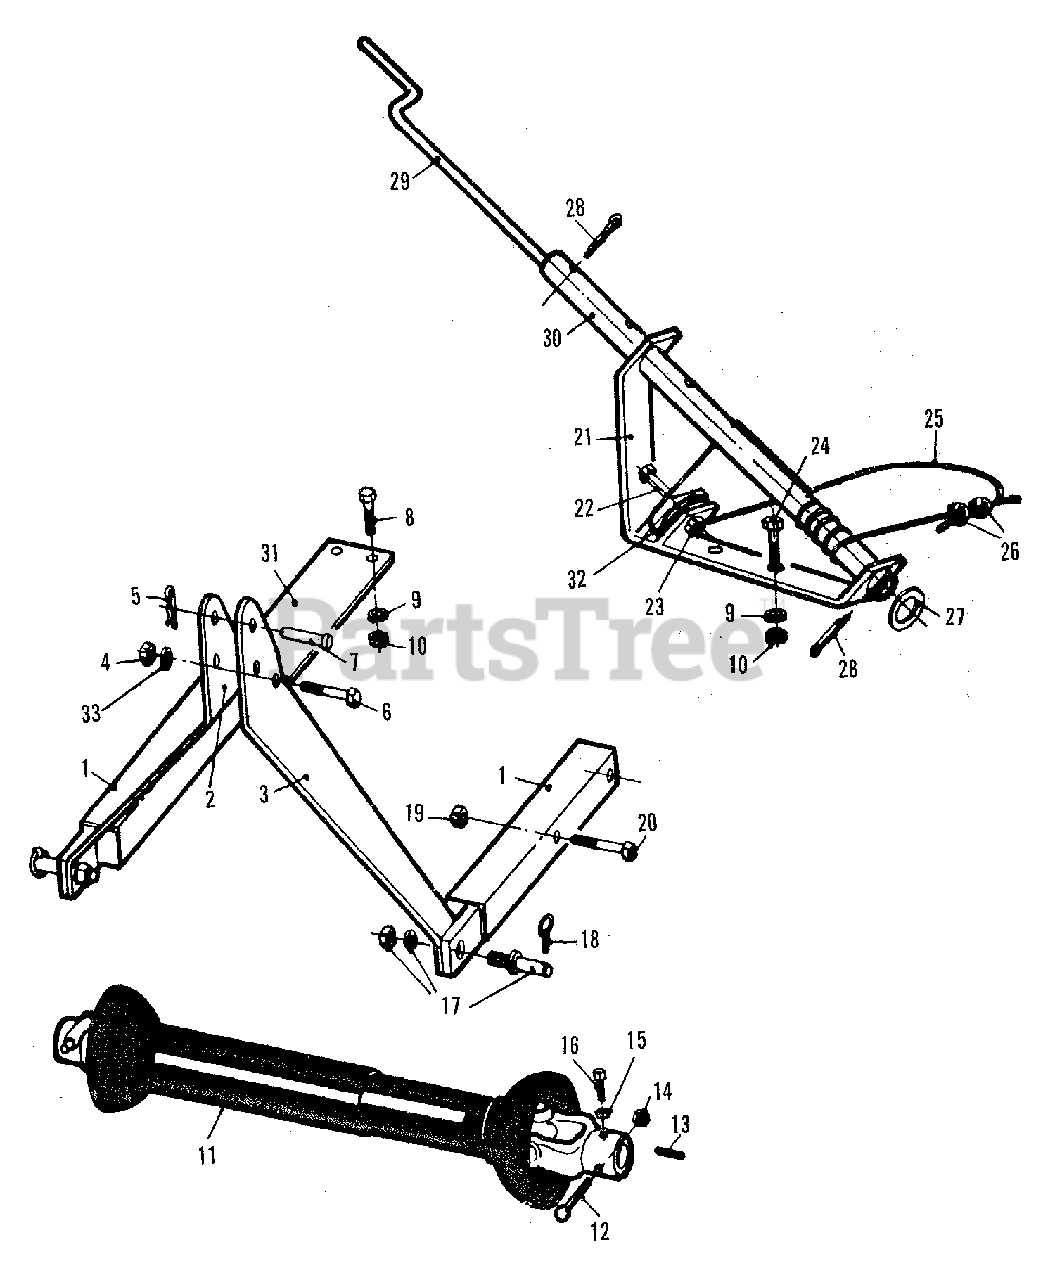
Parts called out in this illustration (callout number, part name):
1	ARM, 3-Point Hitch
2	SUPPORT, Triangle, Left
3	SUPPORT, Triangle, Right
5	PIN, Hitch, 1/4
6	CAPSCREW, 3/4NC x 4
7	PIN, Hitch (Top Link) (Cat 2)
8	CAPSCREW, 1/2NC x 2
9	LOCKWASHER, 1/2
11	SHAFT ASSEMBLY, PTO, Complete
12	CAPSCREW, 5/16NC x 3
13	KEY, 1/4 x 1/4 x 1-1/2
14	LOCKNUT, 5/16NC
16	SETSCREW, Square Head, 3/8NC x 1
17	PIN, Hitch (Lower Link) (Cat. 1)
20	CAPSCREW, 5/8NC x 4
21	STAND, Chute Turner
22	CAPSCREW, 1/2NC x 2
23	LOCKNUT, 1/2NC
24	CAPSCREW, 1/2NC x 1-1/2
25	CABLE, Control, 1/8" x 72" Long
26	CLAMP, Cable
28	PIN, Cotter, 5/16 x 2
30	SLEEVE, Chut Turner
31	BAR, 3-Point Hitch, Upper
32	PULLEY, Wheel
